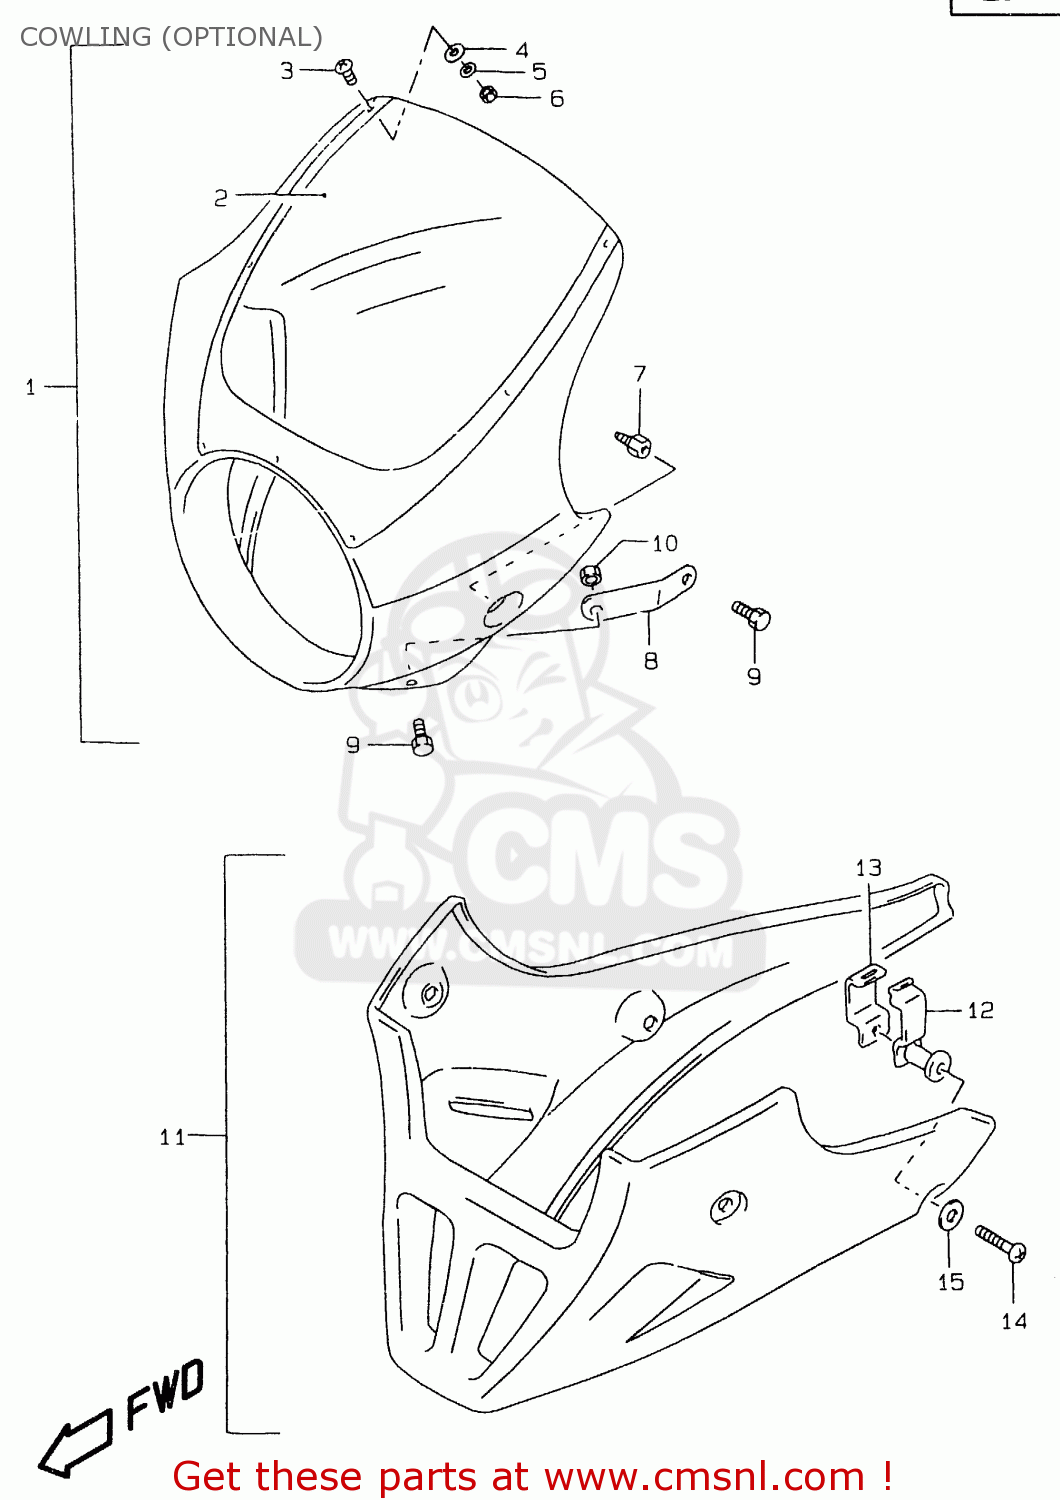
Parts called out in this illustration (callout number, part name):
1	COWLING ASSY,UPR(RED)
2	SCREEN,COWLING
3	SCREW
4	WASHER
5	WASHER,LOCK
6	NUT
7	BOLT,UPR COWLING HEADLAMP
8	BRACE,UPR COWLING
9	BOLT
10	NUT 6MM
11	COVER SET,UNDER COWL
12	BRACKET,UNDER COWLING OUTER
13	BRACKET,UNDER COWLING INNER
14	SCREW
15	WASHER(6.5X18X1.6)
